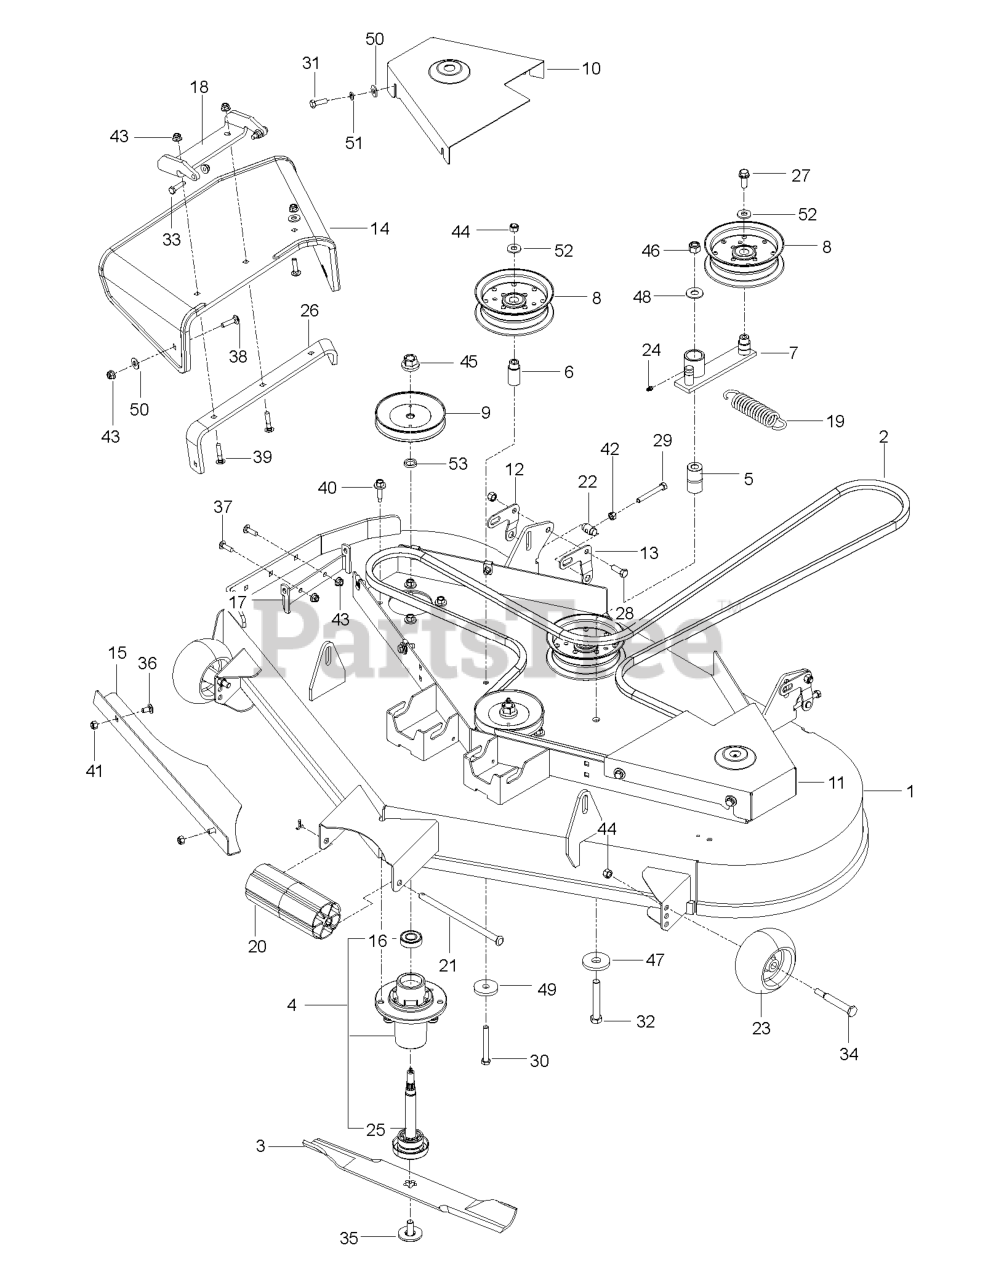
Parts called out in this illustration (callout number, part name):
1	DECK SVC MZT 52 W/DECALS.ORNG
2	BELT, B, 148.5
3	BLADE, 18"
4	MANDREL ASM, CAST IRON
5	PIVOT BUSHING
6	IDLER BUSHING
8	PULLEY, IDLER
9	PULLEY MANDREL
10	BELT SHIELD, RIGHT 52, ORG
11	BELT SHIELD, LEFT 52, ORG
12	BRACKET.RT.PNT.MS431
13	BRACKET.LH.PNT.MS431
14	CHUTE, RUBBER DISCHARGE 52/61"
15	CONFINEMENT PLATE, 52"
17	BRACKET.M-ZT.CHUTE(ORG)
18	PIVOT BRACKET - CHUTE
20	NOSE ROLLER 48"
21	ROD.ROLLER.NOSE.NARROW.48"
22	TRUNION, PITCH
23	WHEEL GAGE DONUT
24	ZERK
25	SHAFT ASM MANDREL
26	BRKT, REINF - CHUTE 52/61"
27	4CS 3/8C X 1 SERRATED HEAD
29	HCS 5/16-18 X 2-1/2 GR 5 ZD
30	BOLT.HEX.FIN.3/8-16 X 3.GR5
31	BOLT.FIN.HEX.5/16-18UNC X 1.00
32	HCS 1/2-13 X 3-1/4 GD 5 ZD
33	BOLT.5/16-18X1-1/4 FULL.THREAD
34	BOLT, SHOULDER
35	BOLT.WASHER.ASM.7/16-2
36	BOLT.CARR.5/16-18X5/8.SHORT
38	BOLT, CARRIAGE 5/16X1-1/4
39	BOLT
40	SCREW, WASHER HEAD
41	NUT.71038.31-18.HEX.NYLOCK
43	5/16-18 NYLOC FLANGE NUT
44	NUT 3/8-16 NYLOC
45	NUT.FLANGE.LOCK.TOP
46	NUT.LK.W/WSH.1/2.
47	WASHER, SUPPORT
48	WASHER 1/2 FLAT
49	SPINDLE WASHER
50	WASHER.5/16.FLAT.STE.STD.
51	WASH.5/16.SLW.ZD
52	RP WASHER 3/8 FLAT
53	WASHER.SPACER.MANDREL
